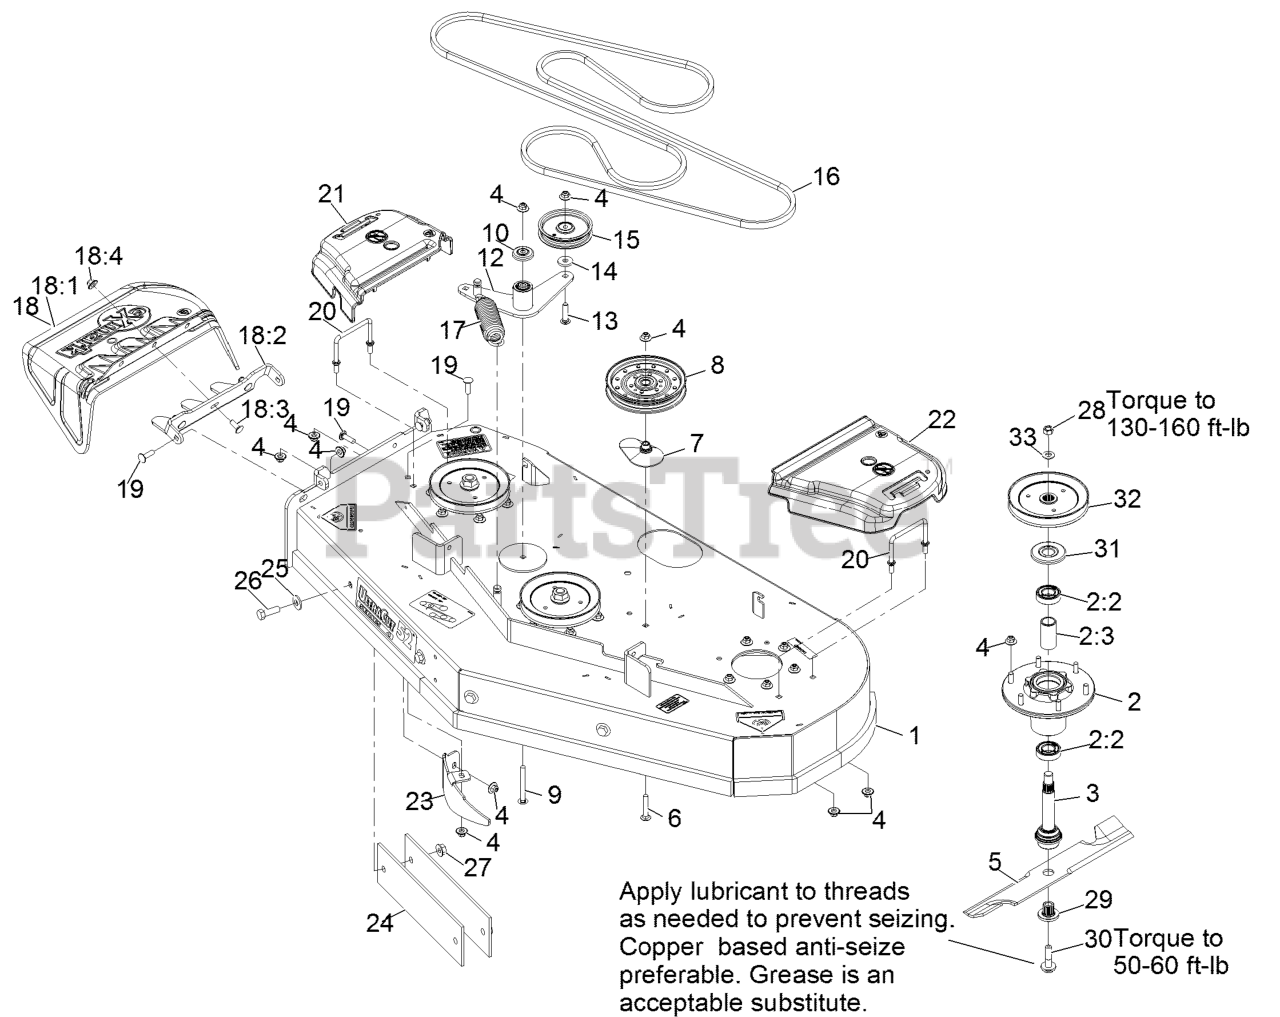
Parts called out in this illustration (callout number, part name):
1	DECK ASM-524
2	ASM-CUTTER HSG WITH BEARINGS
2:2	BEARING-BALL
2:3	SPACER-BEARING
3	ASM-SPINDLE AND SEAL
4	Nut-Nyloc 3/8-16 Flg
6	Bolt-Carriage 3/8-16 X 2 1/4
7	SPACER-PULLEY
9	SCREW-CARR
10	GUARD-TOP
12	IDLER ARM ASM W/BEARINGS
13	SCREW-CARR SPECIAL
15	PULLEY-IDLER
16	BELT-V
17	SPRING-EXTENSION
18	ASM,DISCHARGE CHUTE
18:1	CHUTE,DISCHARGE
18:2	BRACKET,DISCHARGE CHUTE
18:3	SCREW-CARR
18:4	Nut-Nyloc 3/8-16 Flg
19	Bolt-Carriage 3/8-16 X 1 1/4
20	WIREFORM-COVER
21	COVER-BELT, RH
22	COVER-BELT, LH
23	BAFFLE-DOGLEG, LZ-VT52
24	BAR,WEIGHT
25	WASHER-SPRING
26	SCREW-HH
27	NUT-HHF
28	NUT-HEX
29	BUSHING,SPLINED
30	SCREW,SEMS 1/2-20 X 2.19
31	GUARD,BEARING TOP .989
32	SHEAVE,BLADE DRIVE 6.50
